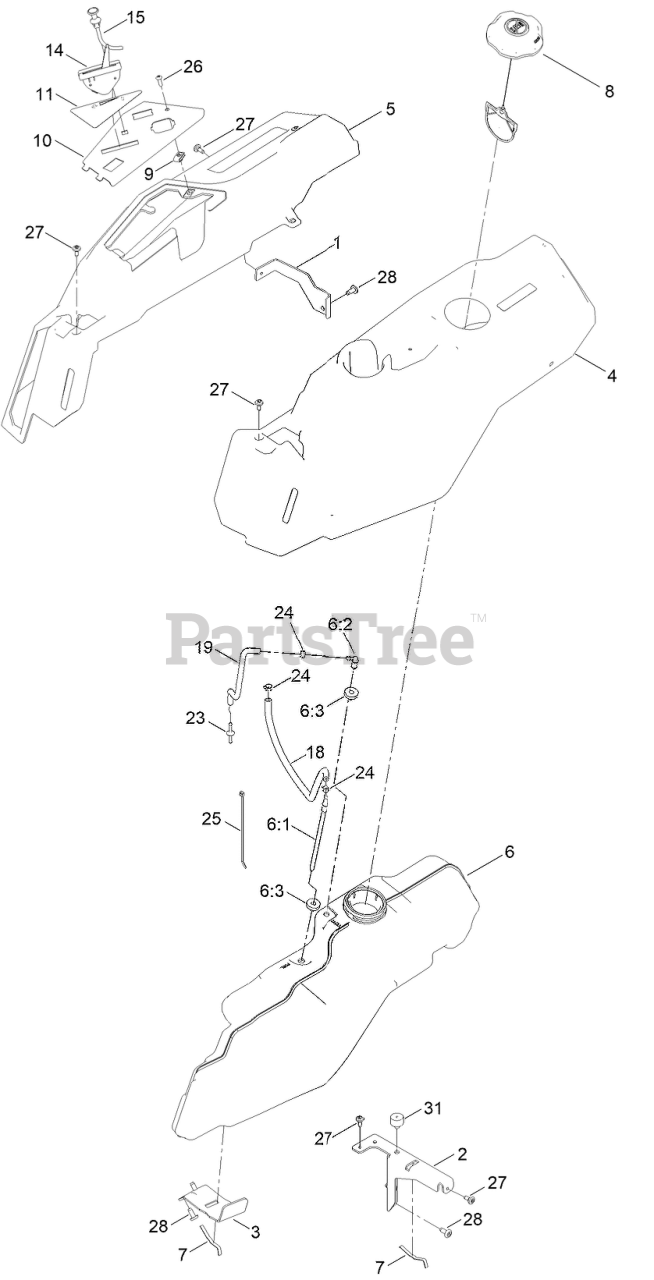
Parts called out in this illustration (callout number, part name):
1	BRACKET-POD
2	SUPPORT-POD, LH
3	SUPPORT-TANK, FUEL
4	POD-LH
5	POD-RH, MYRIDE
6	TANK-FUEL ASM
6:1	CONNECTOR-ELBOW, 90 DEG
6:2	FITTING-ELBOW 90
6:3	BUSHING
7	SPRING
8	CAP-FUEL, RATCHETING
10	PANEL - CONTROL
11	DECAL-PANEL, CONTROL
14	CABLE-THROTTLE
15	CABLE-CHOKE
18	HOSE-FUEL
19	HOSE-FUEL
23	ADAPTER ORIFICE
24	CLAMP-HOSE
25	TIE-CABLE
26	SCREW-PRH
27	SCREW-SHOULDER
31	BUMPER-GROMMET
